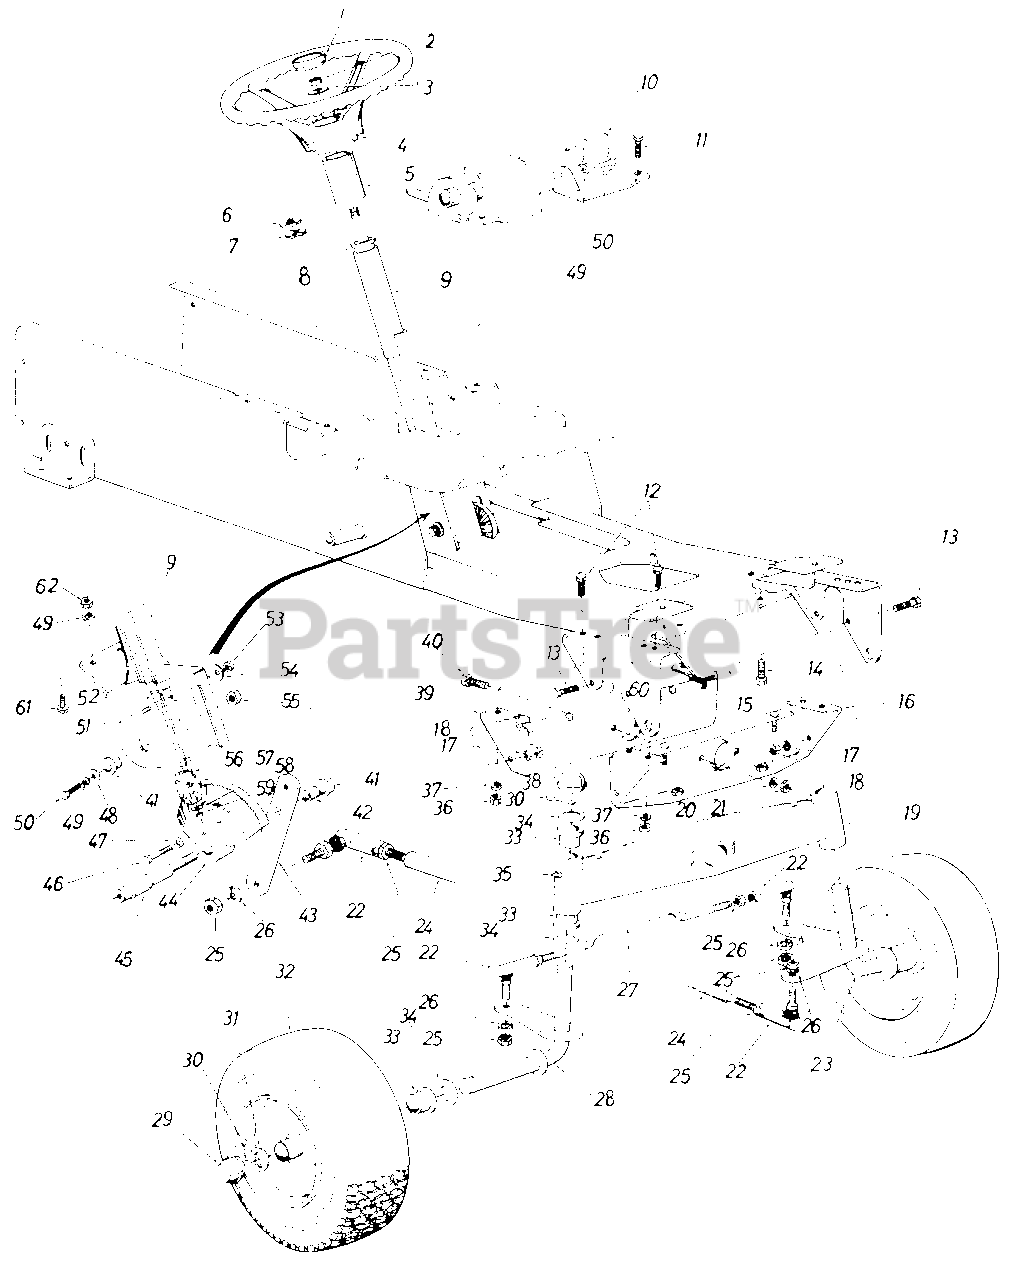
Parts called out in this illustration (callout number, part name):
1	Steering Wheel Cap
2	Hex Cent. L-Nut 5/16-18 Thd.
3	Bell-Wash.
4	Steering Wheel
5	Steering Tube-Outer
6	Double "D" Fl-Wash.
7	Wave Wash. .660 I.D. x .88 O.D.
8	Ball Brg. .63 I.D. x 1.38 O.D.
10	Dash Panel Base Plate Ass'y
11	Hex Self-Tap Scr. 3/8-16 x .75" Lg.
12	Hex Scr. 3/8-16 x 1.50" Lg.
13	Hex Scr. 3/8-16 x 1.00" Lg.
14	Hex Wash. S.F. Tap Scr. 3/8-16 x 1.25" Lg.
15	Dust Shield
18	Hex Nut 3/8-16 Thd.
19	Pivot Bar Ass'y.
20	Bell-Wash. 3/8" Scr.
21	Hex Cent. L-Nut 3/8-16 Thd.
22	Drag Link End
23	Axle Ass'y.-L.H.
24	Drag Link
25	Hex Nut 1/2-20 Thd.
26	L-Wash. 1/2" Scr.
27	Tie Rod
28	Axle Ass'y.-R.H.
29	Dust Cover
30	Cotter Pin 3/16" Dia. x 1.50" Lg.*
31	Fl-Wash. 1.00" I.D. x 1.62"O.D.
33	Flange Brg. 1.00" I.D.
34	Fl-Wash. 1.00" I.D. x 1.62"O.D.
35	Grease Fitting
36	Hex Nut 3/8-16 Thd.
37	L-Wash. 3/8" Scr.
38	Dust Cover
40	Hex Scr. 3/8-16 x 2.50" Lg.
41	Flange Brg. w/Flats .753 I.D.
42	Steering Gear Shaft Spacer
43	Steering Arm
44	Bevel Gear
45	Steering Gear Shaft
46	Hex Scr. 3/8-16 x 1.50" Lg.
47	L-Wash. 3/8" Scr.
48	Fl-Wash. .406 I.D. x 1.25"O.D.
49	L-Wash. 3/8" Scr.
50	Hex Scr. 3/8-16 x .75" Lg.
51	Nylon Hex Scr. 3/8-16 x 1.25" Lg.
52	Steering Shaft
53	Hex Jam Nut 3/8-16 Thd.
54	Bell-Wash. .400 I.D. x 1.13 O.D.
55	Hex Ins. L-Nut 1/2-20 Thd.
56	Hex Flange Brg. .630 I.D.
57	Pi n ion Gear
58	Fl-Wash. 3/8" Dia.
59	Hex Cent. L-Nut 5/16-24 Thd.
62	Hex Nut 3/8-24 Thd.
